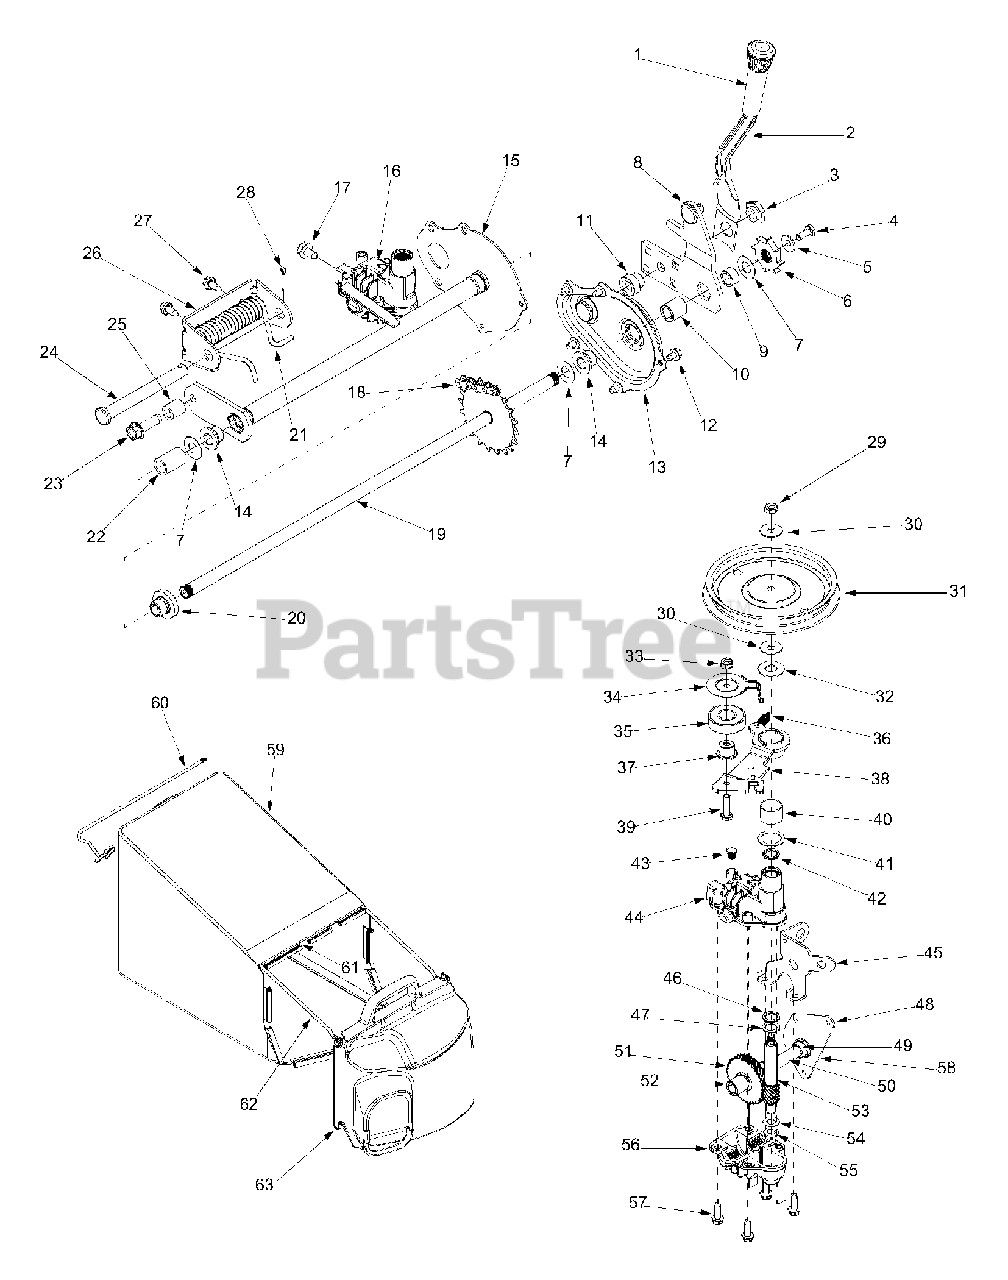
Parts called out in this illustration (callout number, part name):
2	Spring Lever
3	Shoulder Nut .825 x .165 Lg.
4	Cap Screw 1/4-20 x .620
5	Bell Washer .285 ID x .75 OD
6	Wheel Rachet
7	Flat Washer .508 ID x 1.0 OD
9	Spacer .510 ID x .70 OD
10	Sleeve Bearing .504 ID x .830 OD
11	Shoulder
12	Tap Screw 1/4-20 x .375
16	Transmission Assembly
17	Hex Screw 5/16-18
18	Chain
19	Rear Axle Assembly
20	Flange Bearing .506 ID x .715 Lg
21	Torsion Spring
22	Spacer .550 ID x .750 OD
23	Screw 3/8-16 x .25
24	Clevis Pin .50 Dia x 4.82 Lg.
25	Spacer .385 ID x .624 OD
28	Cotter Pin
29	Hex Jam Nut 5/16-24
30	Bell Washer .325 ID x .930 OD
31	Pulley
32	Flat Washer .510 ID x 1.120 OD
33	Hex Jam Nut 1/4-28
34	Belt Keeper
35	Bearing
36	Extension Spring
37	Flange Spacer
38	Idler Bracket Assembly
39	Hex Cap Screw 1/4-28 x 1.0
40	Bearing Sleeve
41	Flat Washer .885 ID x 1.45 OD
42	Oil Seal
44	Upper Housing Assembly
47	Thrust Washer .504 ID x .70 OD
48	Pivot Bracket
49	Flange Bearing
50	Output Shaft 6T
51	Gear 34T
52	Bearing
53	Pinion Shaft 10T
54	Thrust Washer 3/8 x .70
55	Thrust Washer .388 x .625
56	Lower Housing Assembly
57	Hex Screw 1/2-20 x .75
58	Shaft Assembly
59	Grassbag Yardman
61	Pivot Rod
63	Grassbag Cover
